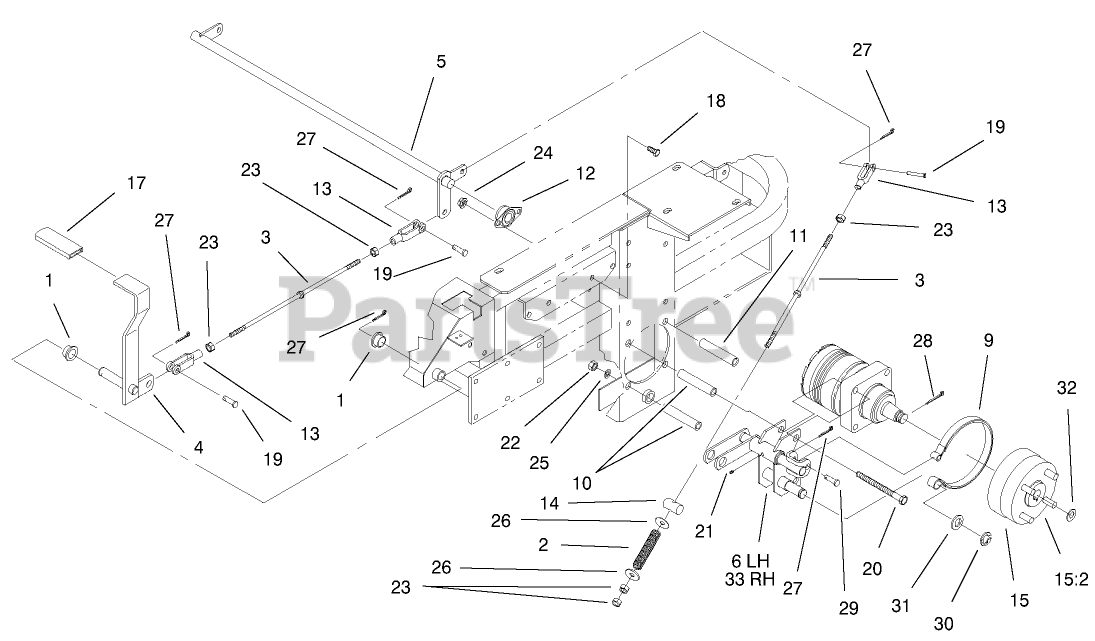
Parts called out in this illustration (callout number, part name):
1	Bearing
2	Spring-Brake
3	Rod-Brake
4	Lever-Brake
5	Shaft-Brake
6	Bracket-Brake LH
9	Band-Brake
10	Spacer
11	Spacer
12	Bearing-Side Flange
13	Yoke-Brake Linkage
14	Pin-Trunion
15	Hub And Drum ASM
15:2	Stud-Wheel
17	Grip-Brake Lever
18	SCREW-HH
19	Pin-Clevis
20	SCREW-HH
21	Fitting-Grease
22	NUT-SQUARE
23	NUT-HEX
24	NUT-HHF, WHIZ
25	WASHER-LOCK
26	WASHER-FLAT
27	PIN-COTTER
28	Pin-Cotter
29	Pin-Clevis
30	Ring-Retaining
31	WASHER-FLAT
32	Spacer
33	Bracket-Brake RH
